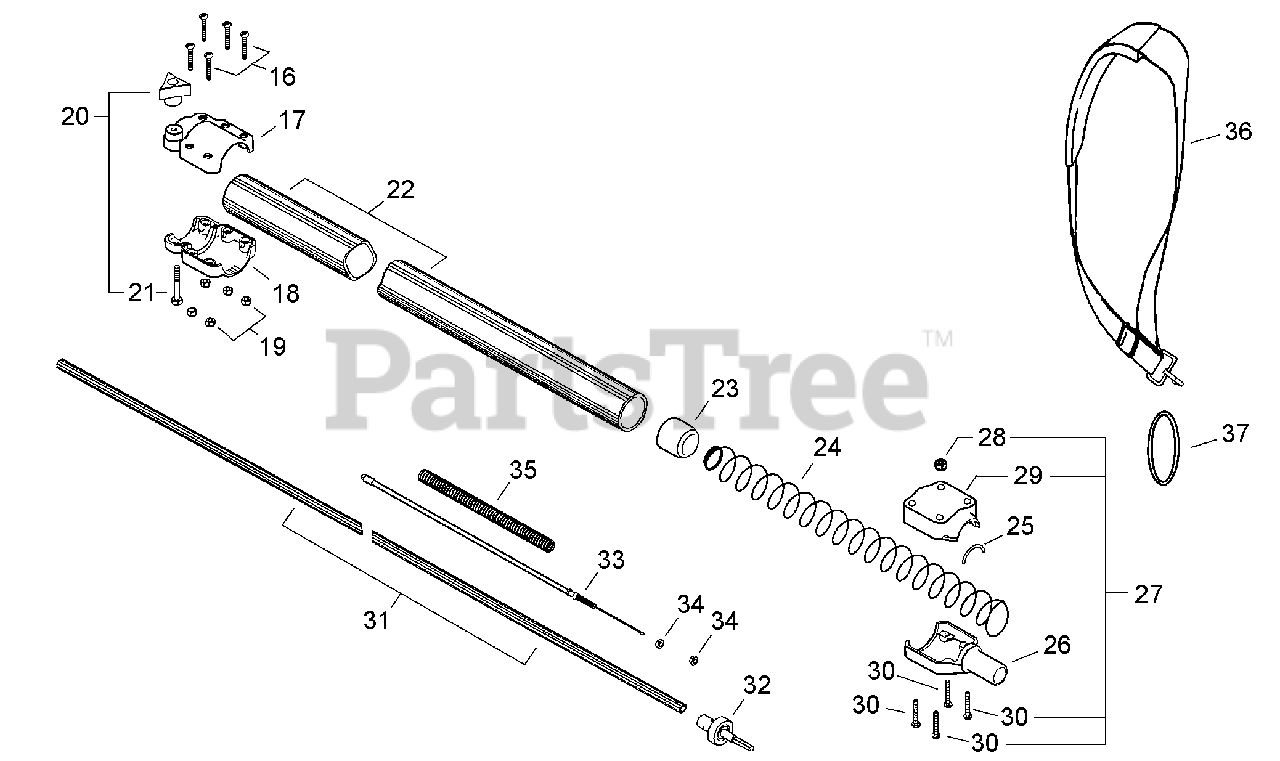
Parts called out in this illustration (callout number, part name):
16	SCREW - 10-24 X 1-1/4"
17	COLLAR, UPPER
18	COLLAR, MAIN PIPE - LOWER
19	LOCKNUT - 10-24
20	THUMBSCREW
21	BOLT - 6
22	PIPE, MAIN - ORANGE
23	BUSHING, FLOATING
26	ADAPTER, LOWER SHAFT TUBE
27	MAIN PIPE CAP ASSY
28	LOCKNUT - 10-24
29	CAP, MAIN PIPE
31	DRIVESHAFT - LOWER
32	CONNECTOR, SHAFT
33	CABLE, THROTTLE
35	TUBE, PROTECTIVE - CORRUGATED
36	SHOULDER STRAP ASSY
